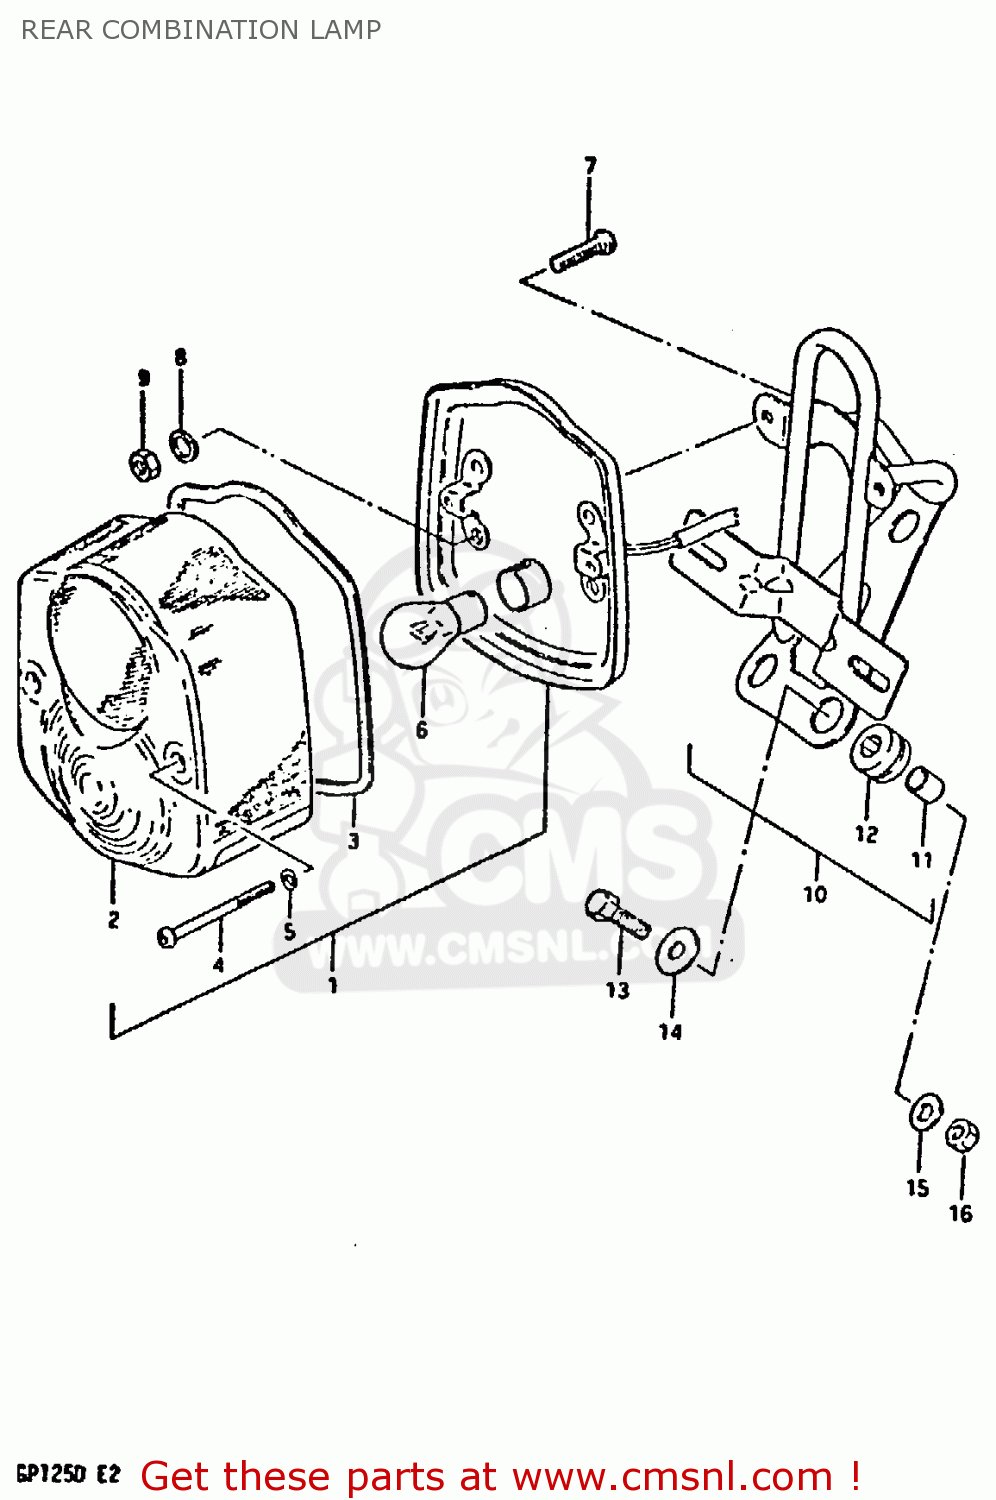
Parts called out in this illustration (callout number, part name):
1	LAMP UNIT, TAIL
2	LENS,RR COMBI
3	GASKET (NAS)
4	SCREW
5	GASKET (NAS)
6	BULB (6V,21/5W)
7	SCREW
8	LOCK WASHER
9	NUT
10	BRACKET ASSY
11	SPACER,RR COMBINATION
12	CUSHION,RR COMBINATION
13	BOLT
14	WASHER (6.5X20X1.2)
15	LOCK WASHER
16	NUT
